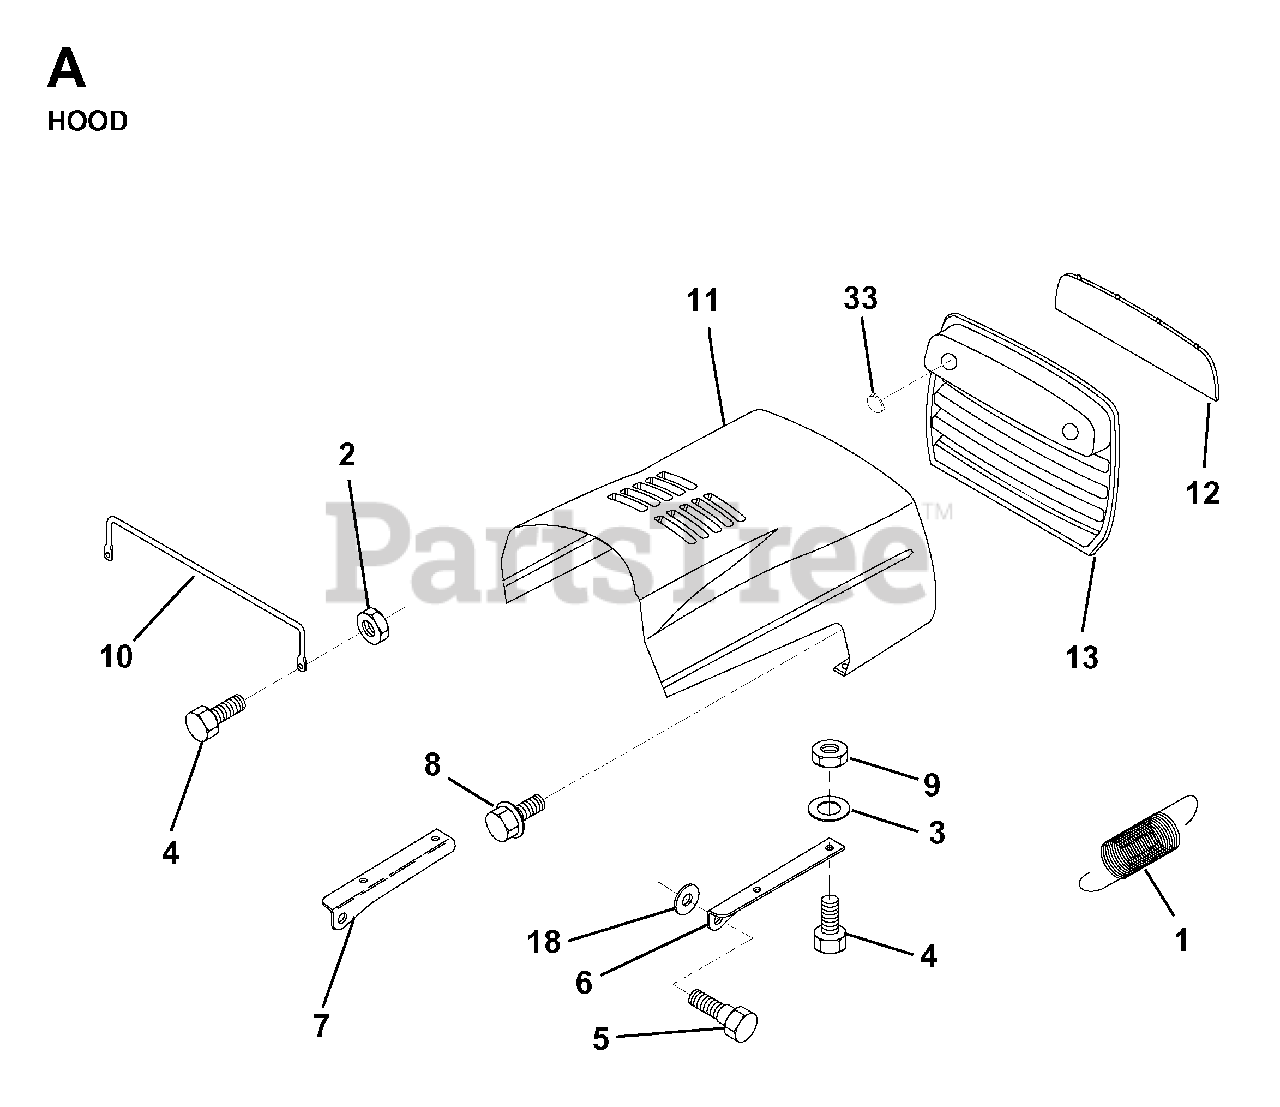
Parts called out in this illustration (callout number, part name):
1	EXT SPRING
2	NUT
4	BOLT
6	BRKT HOOD RH
7	BRKT HOOD LH
9	LOCKNUT
10	BRACE,HOOD
18	WASHER
33	CVR LIGHT SOCKET
